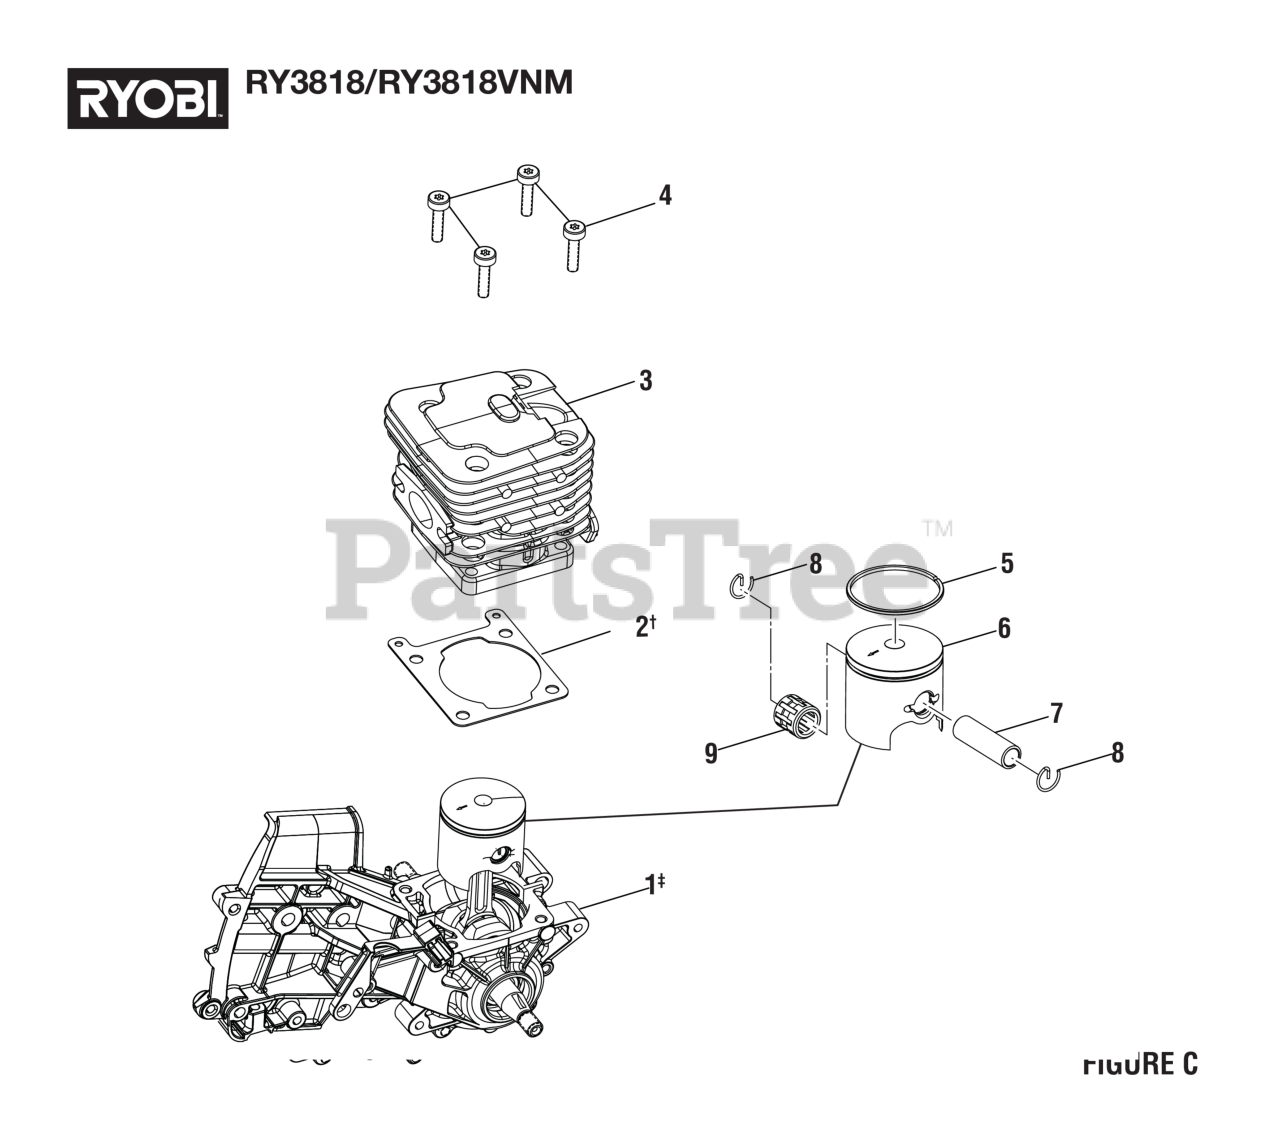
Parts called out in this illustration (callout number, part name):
1	Crankcase & Crankshaft Assembly
2	Crankcase Gasket
4	Cap Screw (M5 x 20 mm, T25 Torx Soc. Hd.)
5	Piston Ring
7	Piston Pin
8	Piston Pin Clip
9	Needle Bearing
